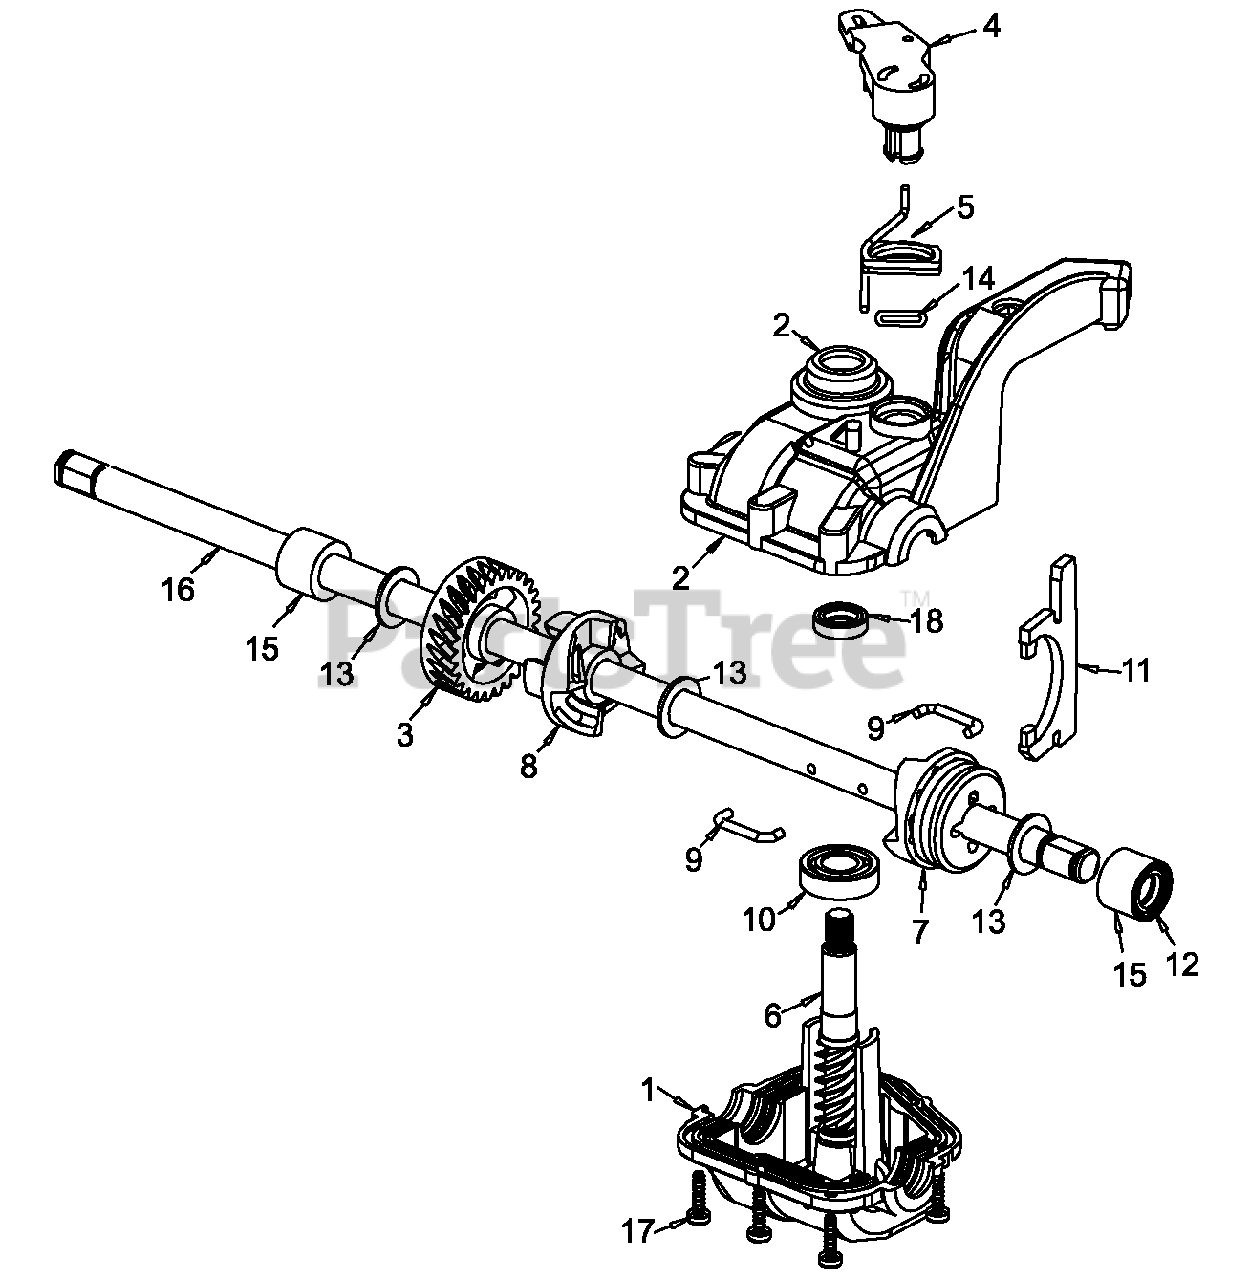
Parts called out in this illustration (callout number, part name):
1	Case, Lower
2	Case, Upper
3	Gear, 27 Teeth
4	Lever, Clutch
5	Spring, Return
6	Shaft, Input
7	Dog, Movable
8	Dog, Fixed
9	Wire, Formed
10	Bearing, Ball
11	Fork, Shift
12	Seal, Output Shaft
13	Washer
14	Seal, Case
15	Bushing
16	Shaft, Output
17	Screw
18	Seal, Input Shaft
18	Kit, Gearcase Replacement
